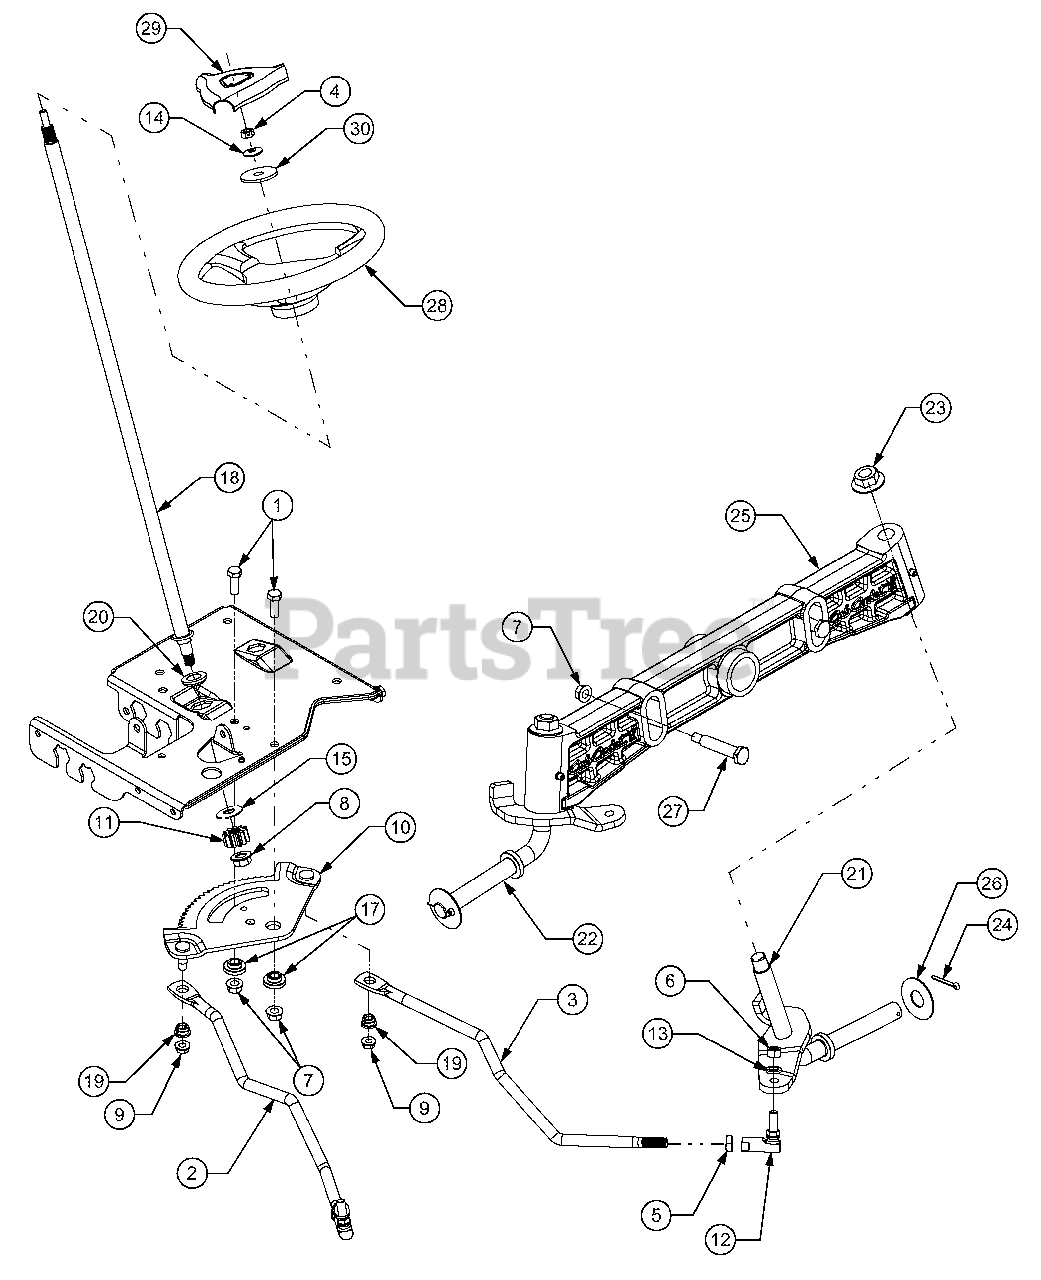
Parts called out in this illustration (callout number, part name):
1	Hex Cap Screw, 3/8-16, 1.00, Gr5, Std
2	Link, Drag, RH
3	Link, Drag, LH
4	Nut, Hex Lock, 5/16-24
5	Nut, Jam, 7/16-20, Gr2
6	Nut, Hex, 3/8-24, Gr5
7	Nut, Flange Lock, 3/8-16
8	Nut, Flange Lock, 7/16-20
9	Nut, Flange Lock, 5/16-18
10	Gear, Steering, 11/90 Ratio
11	Gear, Pinion, Steering
12	Ball Joint, 7/16-20
13	Washer, Lock, 3/8, Regular Duty
14	Washer, Bell, .340 x .872 x .060
15	Washer, Flat, .510 x 1.120 x .060
17	Spacer, Shoulder, 1.00 x .38 x .38
18	Shaft, Steering, .625 OD x 25.00 Lg
19	Bushing, Plastic, .380 ID
20	Bearing, Hex Flange, 5/8
21	Axle Assembly, LH .750 Dia
22	Axle Assembly, RH .750 Dia
23	Nut, Hex, Flange, 5/8-18
24	Pin, Cot, 5/32, 1.25
25	Axle, Pivot, Cast .750 Dia
26	Washer, Flat, .755 x 1.92 x.060
27	Spacer, Shoulder, .500 x 2.230, 3/8-16
28	Wheel, Steering, Soft Grip, Three Spoke
29	Cover, Steering Wheel
30	Washer, Flat, .344 x 1.5 x .10
